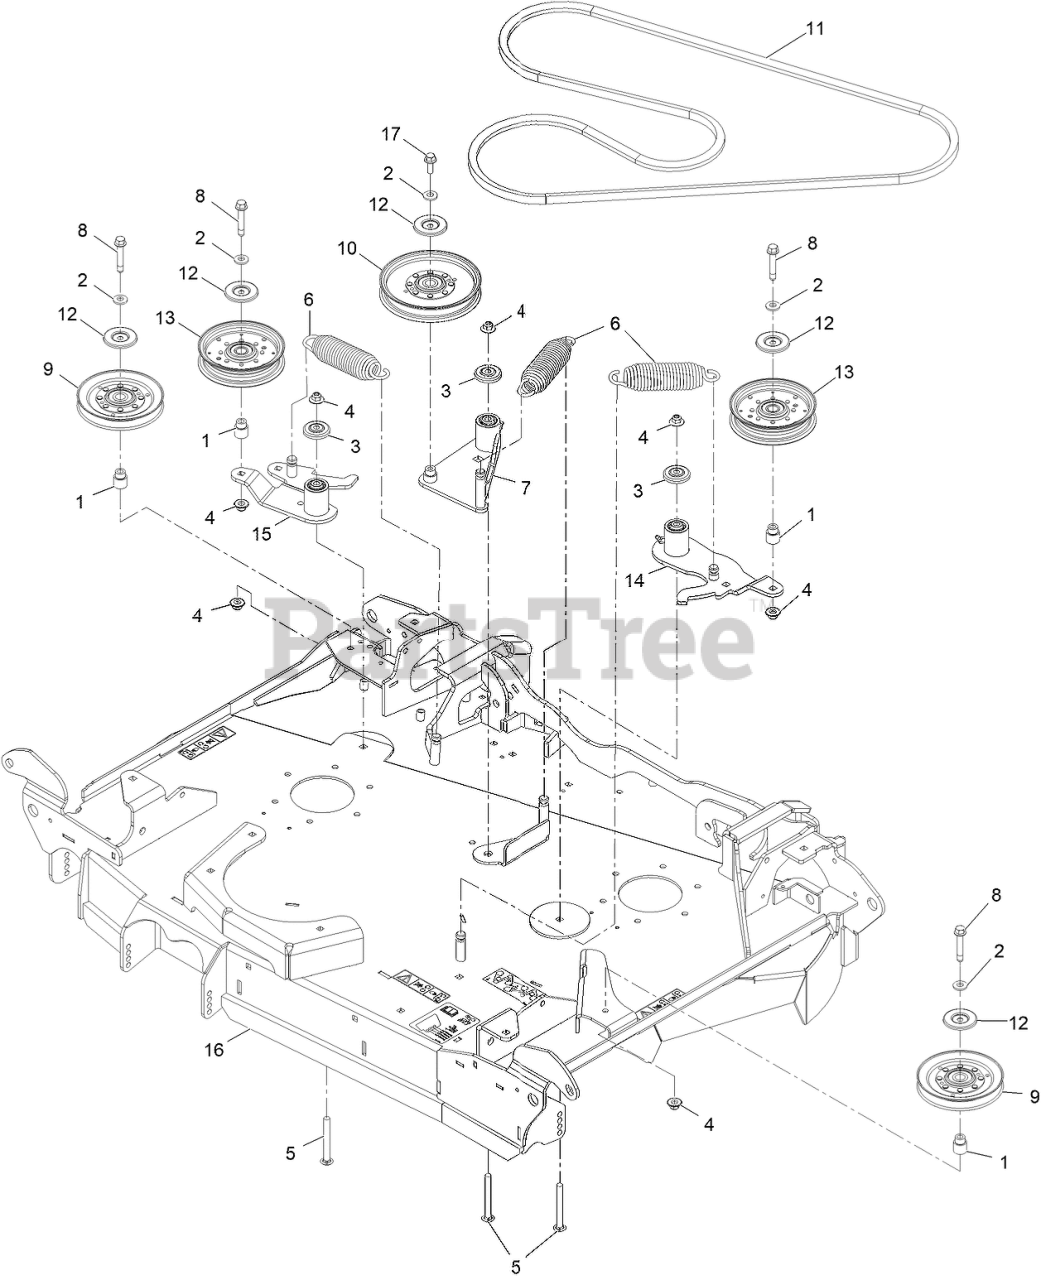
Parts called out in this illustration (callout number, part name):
1	BUSHING-IDLER
2	WASHER-BELLEVILLE
3	GUARD-TOP
4	Nut-Nyloc 3/8-16 Flg
5	BOLT-SHOULDER, CARRIAGE 3/8-16 X 3 1/2
6	SPRING-EXTENSION
7	IDLER ARM ASM
8	SCREW-HHF
9	IDLER-V
10	IDLER-PULLEY
12	SHIELD-DUST
13	PULLEY-IDLER, FLAT
14	IDLER ASM
15	IDLER ASM
16	ASM-DECK, CTR 96/120
17	SCREW-HHF 3/8-16 X 1
